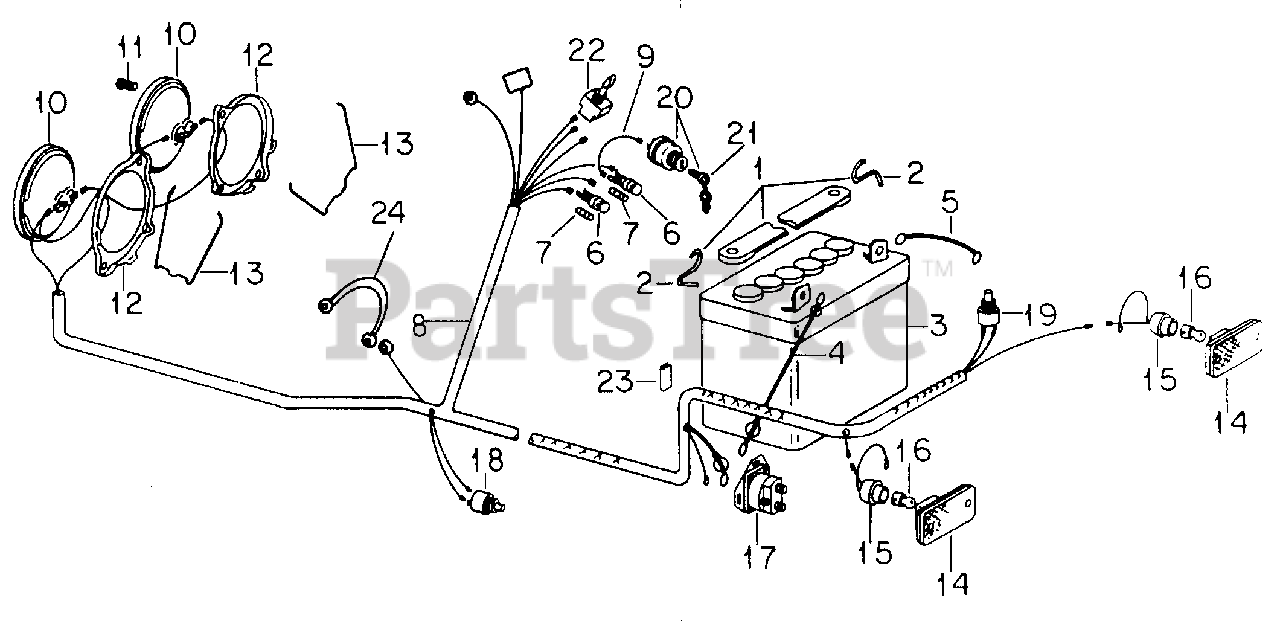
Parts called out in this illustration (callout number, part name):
1	Strap Assy, Battery
2	Hook, Battery Strap
3	Battery, 12 Volt
4	Cable, Battery, Positive
5	Cable, Battery Negative Terminal to Ground
6	Holder, Fuse
7	Fuse, 10 Amp
8	Harness Assy, Main Cable
9	Not used in this application
10	Light, Sealed Beam Head
11	Screw, Headlight Mtg
12	Retainer, Headlamp
13	Spring, Headlamp Retaining
14	Lens Assy, Taillight
15	Cable Assy, Taillight
16	Bulb, Taillight #194
17	Switch, Magnetic
18	Switch, Neutral Start
19	Switch, Neutral Start
20	Switch, Battery Ignition Key
21	Key, Ignition Switch
22	Switch, PTO
23	Not used in this application
24	Cable, Engine to Ground
